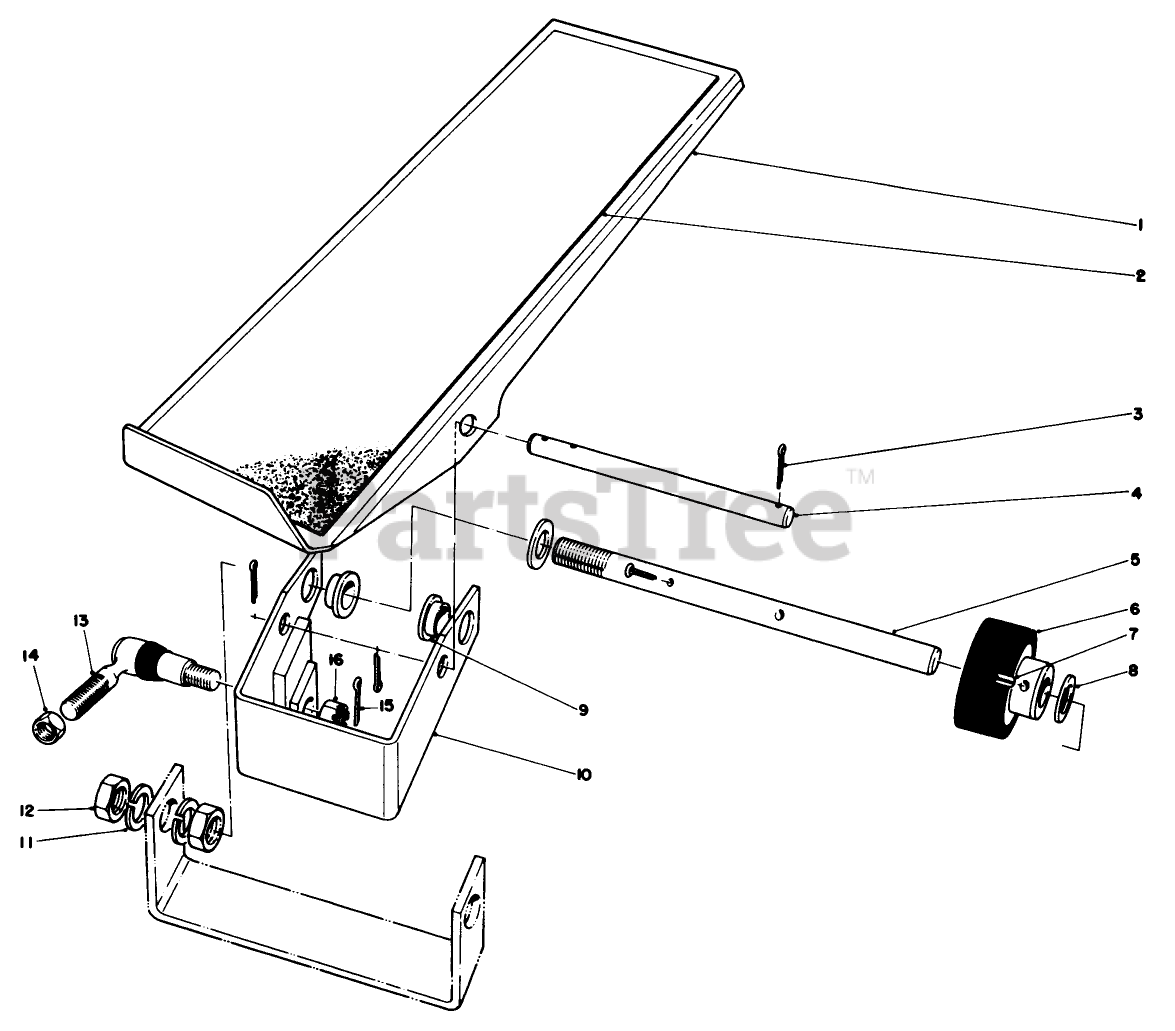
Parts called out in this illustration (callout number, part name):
2	TRACTION PEDAL PAD
3	PIN-COTTER
6	FRICTION WHEEL ASM
7	PIN-SPRING
8	WASHER-FLAT
9	BUSHING-FLANGE
11	WASHER-LOCK
12	NUT-JAM
14	NUT-JAM
15	PIN-COTTER
16	NUT-HEX,SLOTTED
